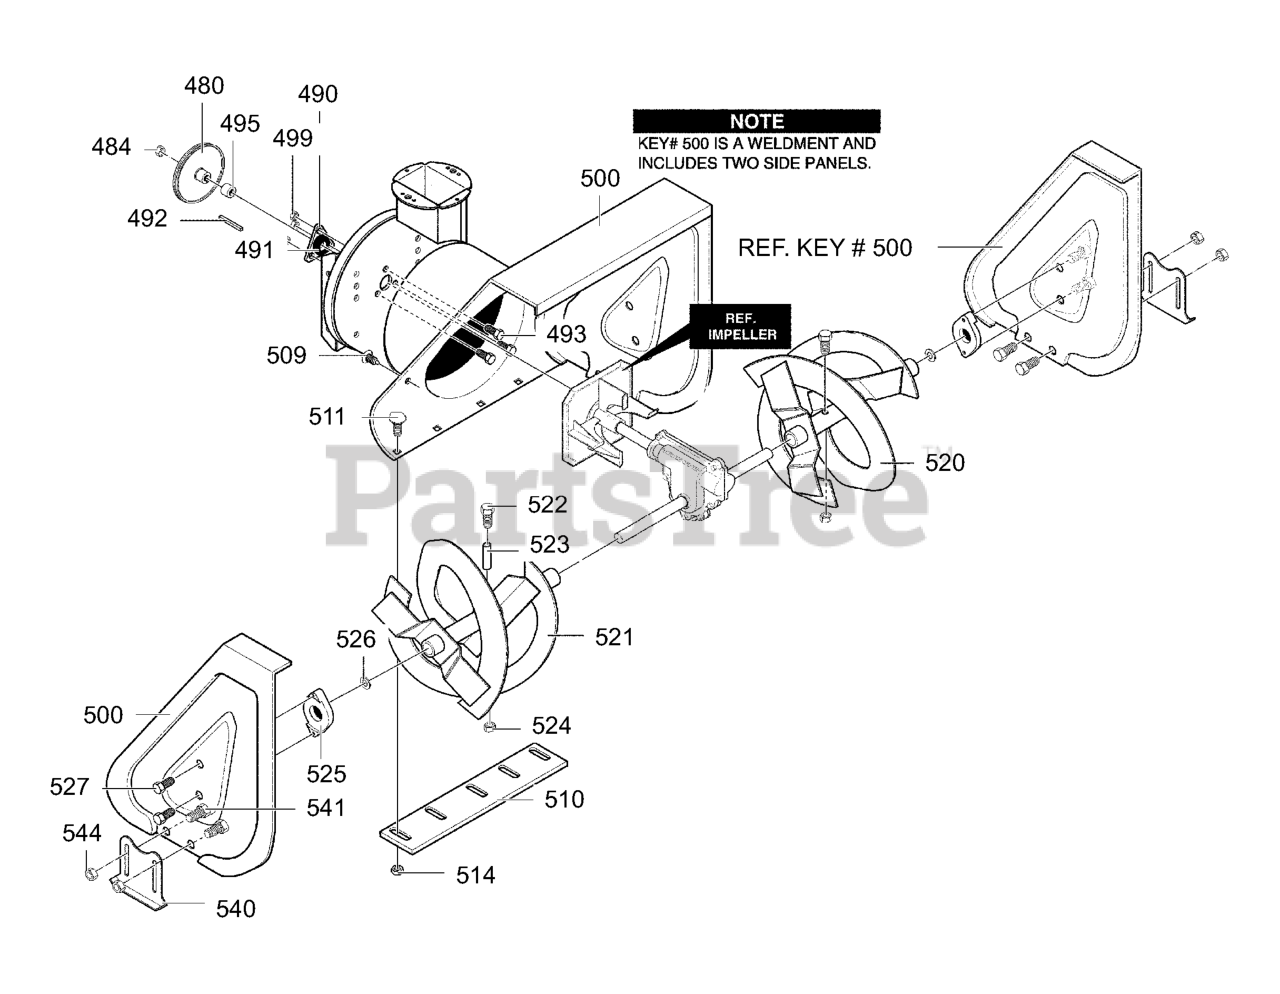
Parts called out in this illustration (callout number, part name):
484	NUT, 1/4-20
490	RETAINER, BALL BRNG
491	BEARING, BALL
492	KEY, SQUARE
493	BOLT, HEX - 0.31-18X0.50
495	SPACER, FRICTION PULLEY
499	NUT, 5/16-18 HEXWDFLLK
500	HOUSING, ASSY
509	PLUG, CHRISTMAS TREE
510	BLADE, SCRAPER
511	BOLT, 1/4-20X.75
520	AUGER, ASSY, LH
521	AUGER, ASSY, RH
522	SCREW, 1/4-20X1.75
523	SPACER, SLEEVE
524	NUT, 1/4-20
525	BEARING,FLANGE
527	SCREW, 5/16-18 x 0.75
540	SKID, HEIGHT ADJUST
541	BOLT, 5/16-18 X .75
544	NUT, 5/16-18 REGHEX
